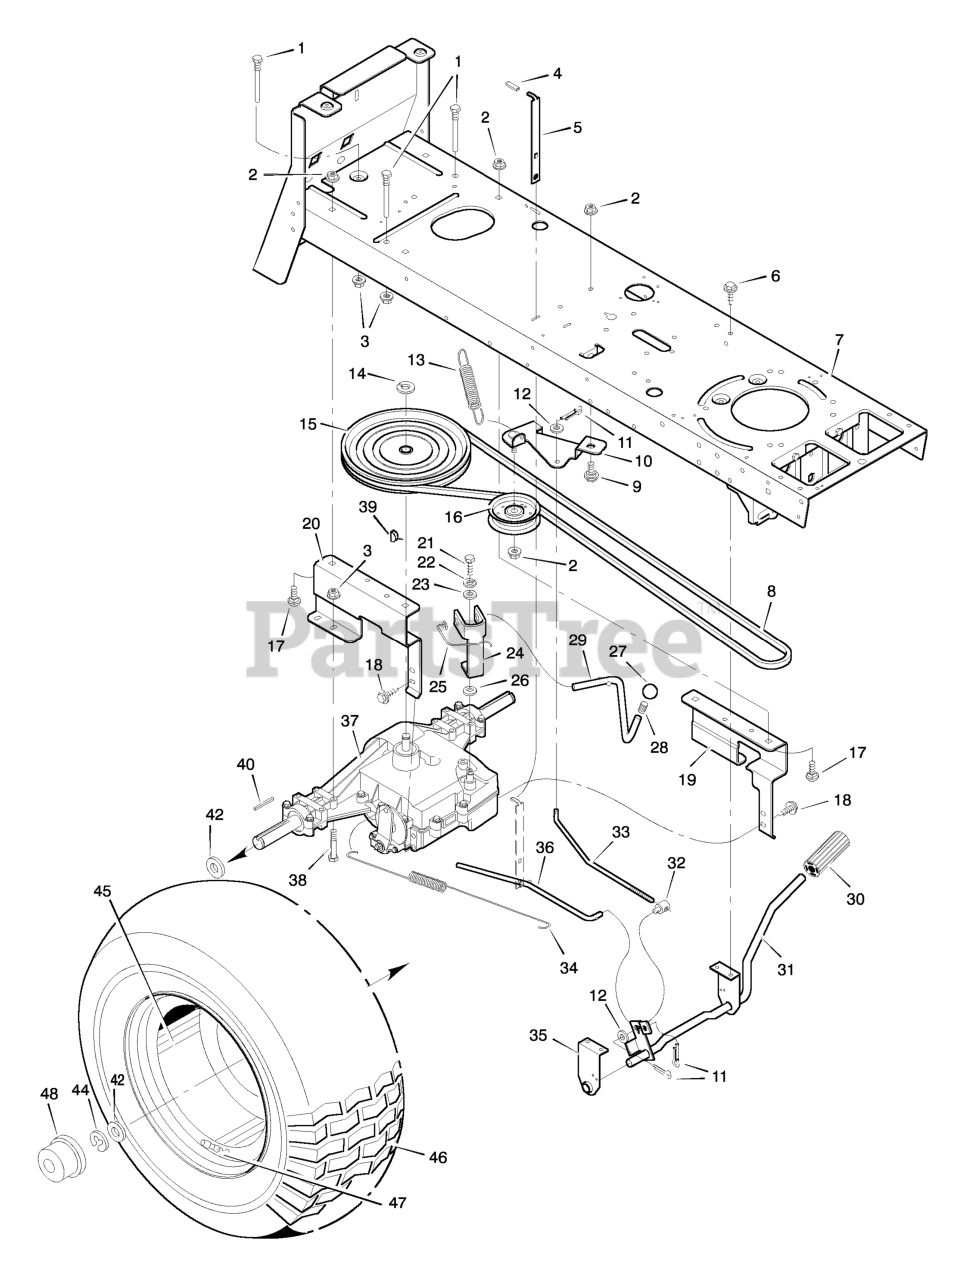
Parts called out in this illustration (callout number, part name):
1	Guide, Belt
2	Locknut, Flange
3	Locknut, Flange
5	Lever, Parking Brake
8	Belt, Motion Drive
9	Bolt, Shoulder
10	Bracket Assembly, Idler
11	Pin, Cotter
12	Washer
13	Spring, Drive Extension
14	Ring, Retainer
15	Pulley, Motion Drive
16	Pulley, Backside Idler
17	Bolt, Carriage
19	Bracket, Left Transaxle
20	Bracket, Right Transaxle
21	Bolt, Hex
22	Lockwasher
24	Yoke, Shift Lever
25	Spring
27	Knob, Shift Lever
28	Ring, Tolerance
29	Lever, Shift
30	Pedal, Clutch/Brake
31	Lever Assembly, Pedal
32	Nut, Adjustable
33	Rod, Clutch
34	Spring, Brake Extension
35	Bracket, Pedal Support
36	Rod, Brake Latch
37	Transaxle, Peerless **
38	Bolt, Hex
39	Key, Woodruff No. 9
40	Key, Square
45	Wheel & Tire Assembly
46	Tire Only *
47	Valve Stem
48	Cap, Hub
